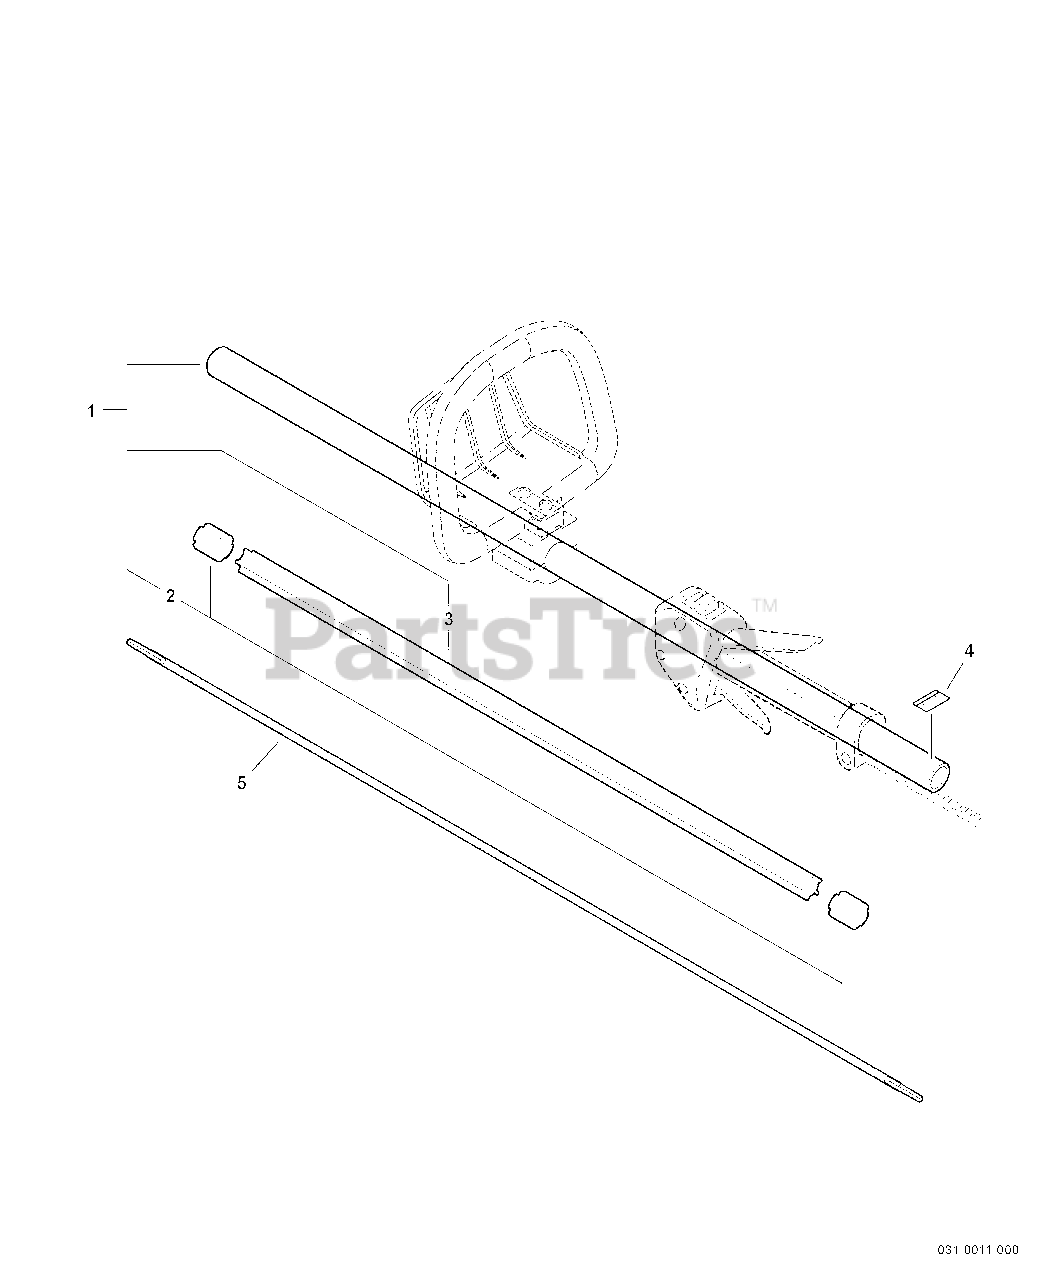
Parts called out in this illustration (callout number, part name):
1	MAIN PIPE ASSY
3	LINER - FLEXIBLE
4	LABEL - ALIGNMENT
5	DRIVESHAFT - FLEXIBLE
